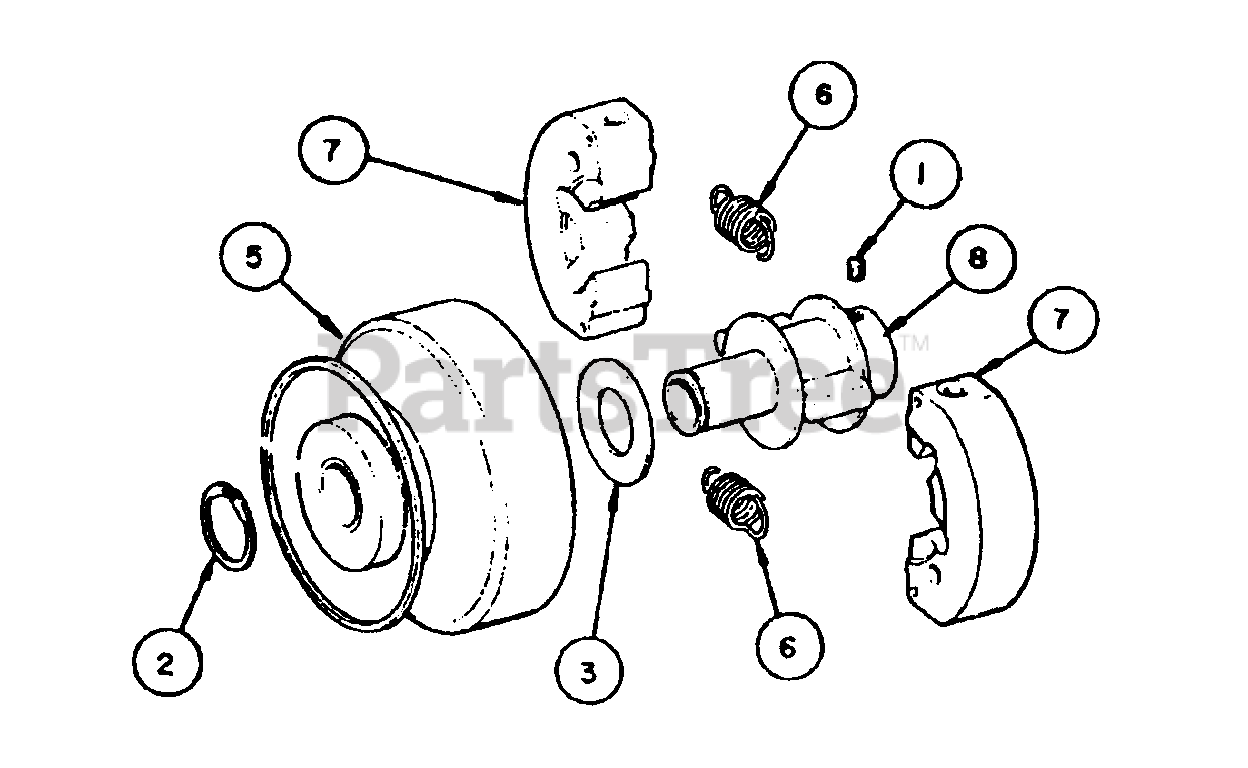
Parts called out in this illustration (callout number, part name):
1	Set Screw
2	Retaining Ring
3	Washer
5	Drum & Bushing
6	Spring
